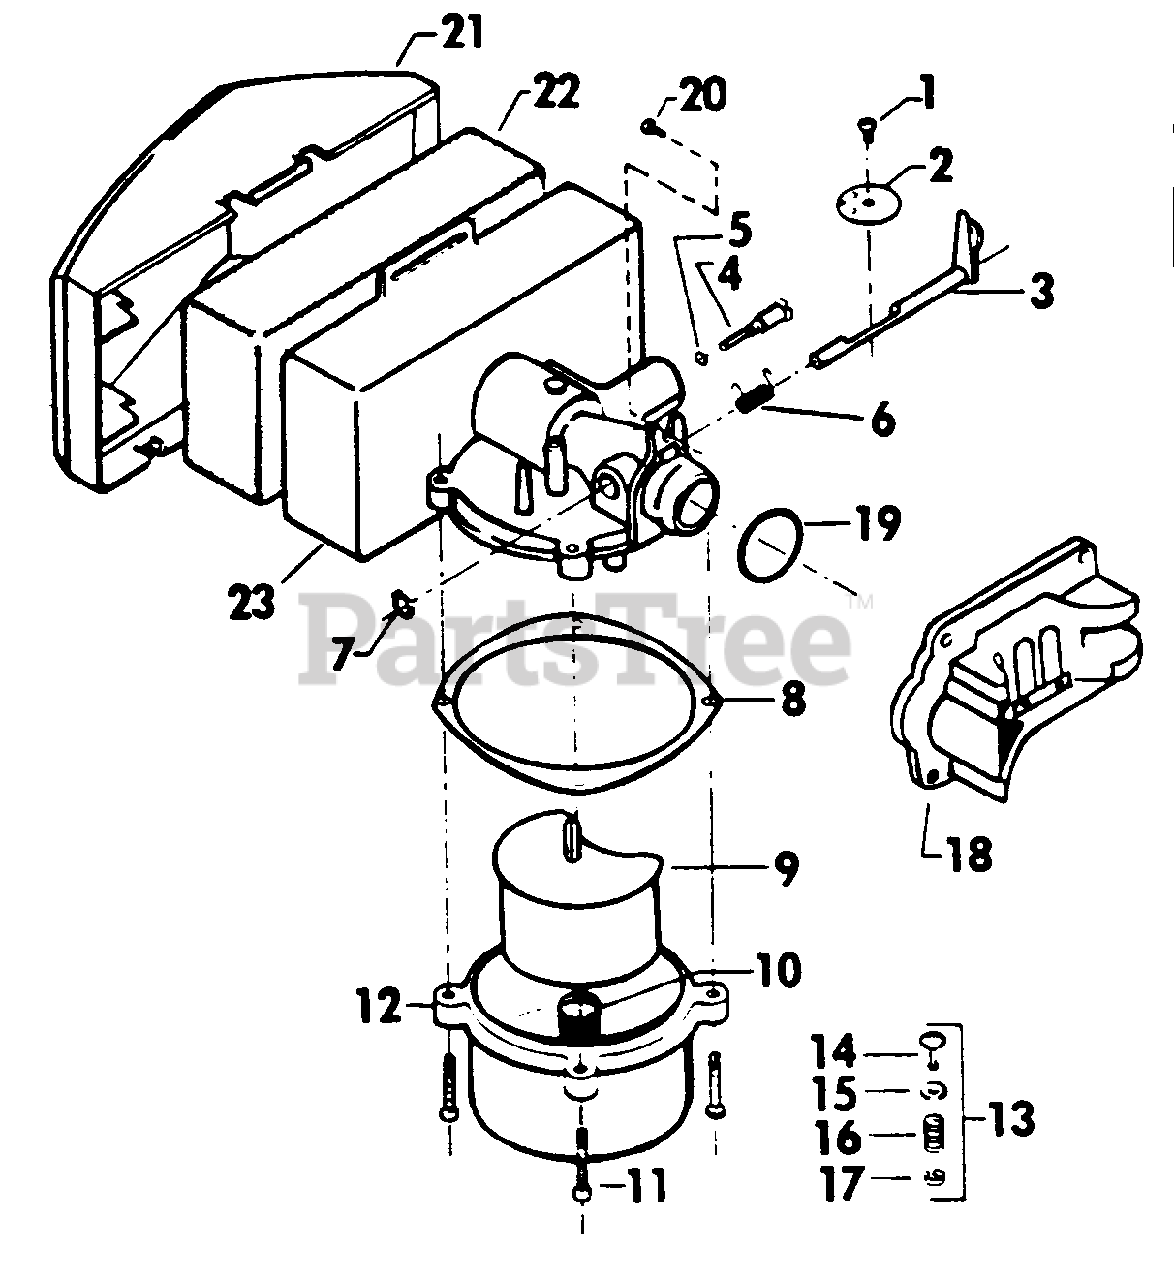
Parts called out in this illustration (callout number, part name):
1	Screw, Disk
2	Disk, Throttle
3	Throttle Shaft
4	Screw, Alt. Adj.
5	O-Ring
6	Spring, Throttle
7	Grip, Ring
8	Gasket, Bowl
9	Float & Valve
10	Spring, Float
11	Screw, Bowl
12	Bowl
13	Dump Valve Assy.
14	Valve Stem
15	Valve Seat
16	Valve Spring
17	Valve Keeper
18	Reed Plate
19	O-Ring
20	Screw, Mfg.
21	Cover, Filter
22	Element
23	Carb. Body Assy.
